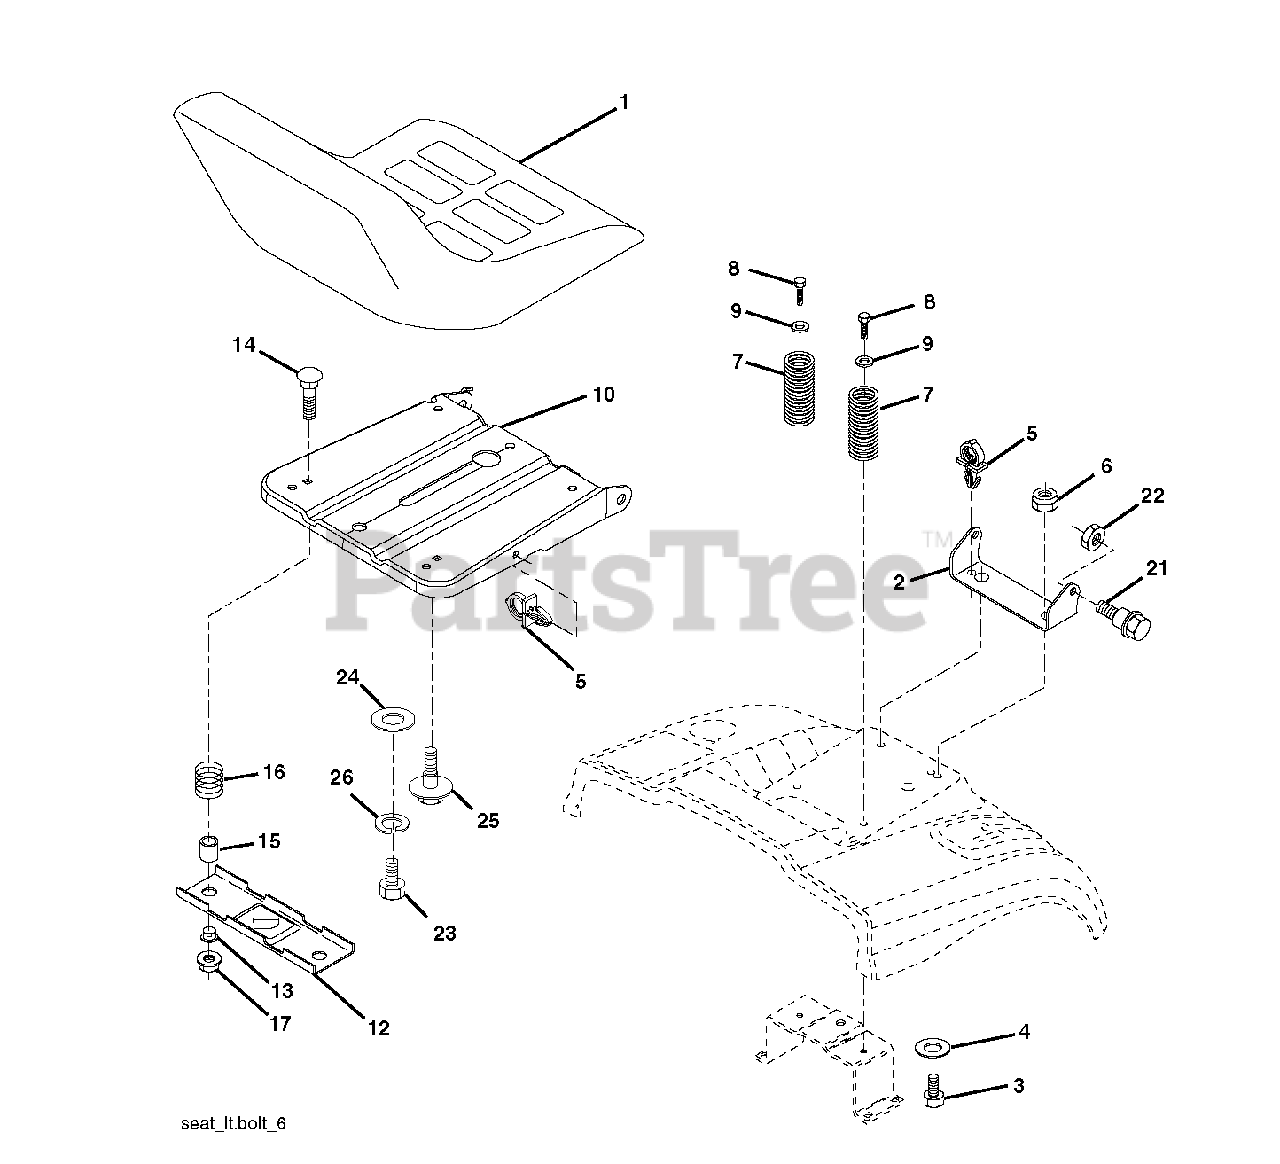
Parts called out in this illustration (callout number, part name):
1	SEAT.XG090.BLK.KB/BLT.NO-LOG
2	SEAT PIVOT BRKT
3	BOLT, HEX 3/8-16X1
6	NUT
7	SPRING COMPRESSION
8	SCREW 3/8-16X1
9	WASHER
10	PAN.ASM.SEAT.1SLOT
12	BRKT.MNTNG.SWITCH.SEAT
14	BOLT.ROUND.HEAD.SQUARE.NECK
15	SPACER SPLIT 28X.96
17	NUT T
21	BOLT.SHOULDER.5/16-18
22	NUT.71038.31-18.HEX.NYLOCK
23	BOLT.HEX.BLACK
